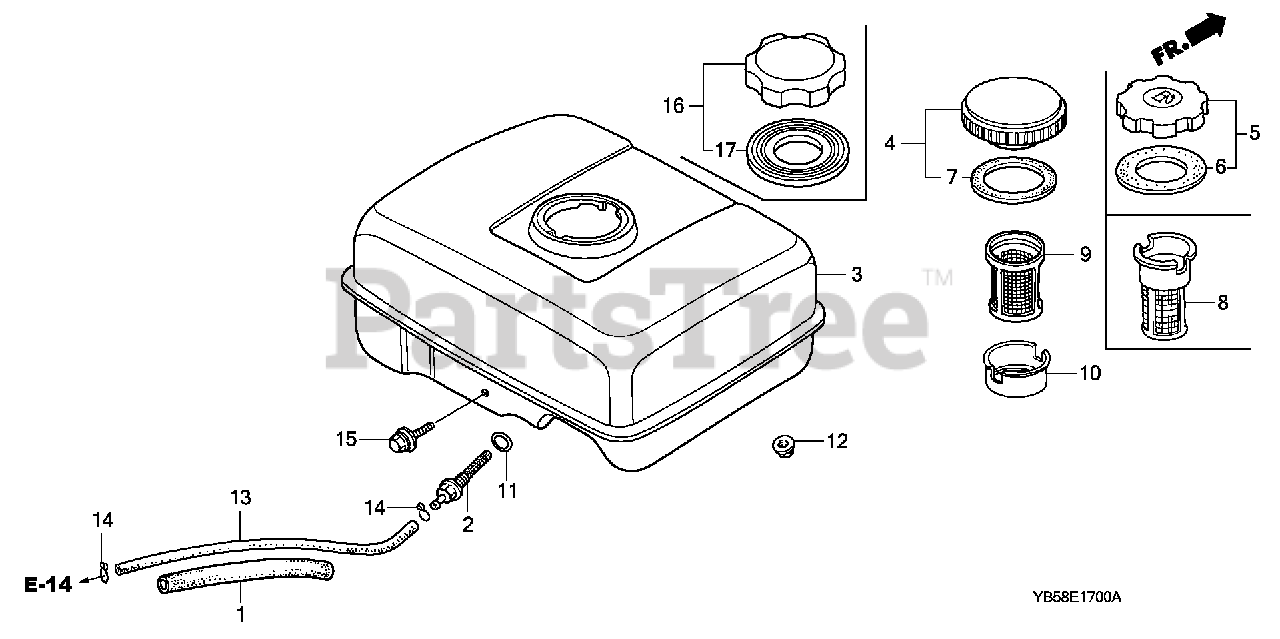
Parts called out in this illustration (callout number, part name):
1	RUBBER, SUPPORTER (107MM)
2	JOINT, FUEL TANK (NOT AVAILABLE)
2	JOINT, FUEL TANK
3	TANK, FUEL *NH31* (MCKINLEY WHITE)
4	CAP, FUEL FILLER (CHROME PLATED)
4	CAP, FUEL FILLER
5	CAP, FUEL FILLER (BLACK)
6	GASKET, FUEL FILLER CAP (39X58X3)
7	GASKET, FUEL FILLER CAP (39X58X3)
8	FILTER, FUEL
9	FILTER, FUEL
10	HOLDER, FUEL FILTER
11	O-RING (14MM) (ARAI)
11	O-RING (14MM) (NOK)
12	NUT, FLANGE (6MM)
13	BULK HOSE, FUEL (4.5X3000) (4.5X140)
14	CLIP, TUBE (B8)
15	BOLT, FLANGE (6X25)
